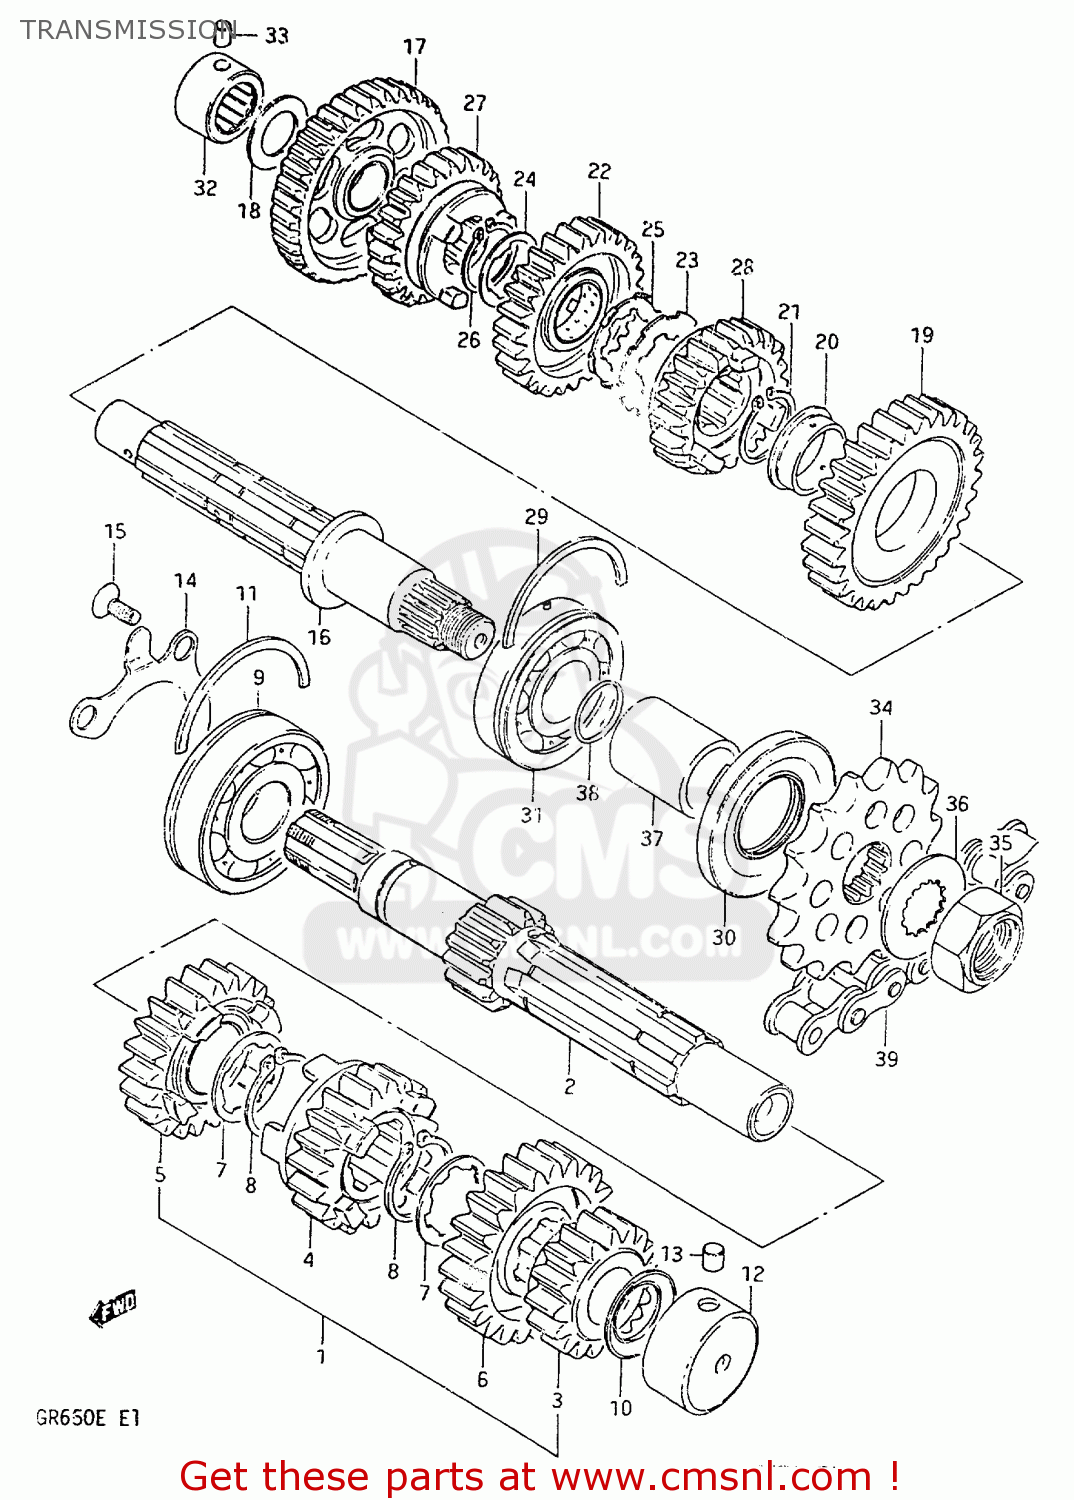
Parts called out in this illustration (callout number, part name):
1	SHAFT,COUNTER
2	SHAFT,COUNTER
3	GEAR,SECOND DRIVE
4	GEAR,THIRD DRIVE
5	GEAR,FOURTH DRIVE
6	GEAR,FIFTH DRIVE
7	WASHER,LOCK
8	RING,SNAP
9	BEARING(25X62X17)
10	SEAL,OIL(20X31.2X2.7)
11	C-RING
12	BEARING(20X34X17.5)
13	PIN
14	RETAINER,BEARING
15	SCREW
16	SHAFT,DRIVE
17	GEAR,FIRST DRIVEN
18	WASHER
19	GEAR,SECOND DRIVEN
20	BUSHING
21	RING,SNAP
22	GEAR,THIRD DRIVEN
23	WASHER,LOCK
24	WASHER,LOCK
25	WASHER
26	RING,SNAP
27	GEAR,FOURTH DRIVEN
28	GEAR,FIFTH DRIVEN
29	C-RING
30	SEAL,OIL(32X62X7)
31	BALL BEARING 25X62X17
32	BEARING(20X34X20)
33	PIN
34	SPROCKET,ENGINE
35	NUT
36	WASHER,LOCK
37	SPACER (25X32X33.7)
38	O RING(D:1,ID:24.5)
39	CHAIN ASSEMBLY,DRIVE
